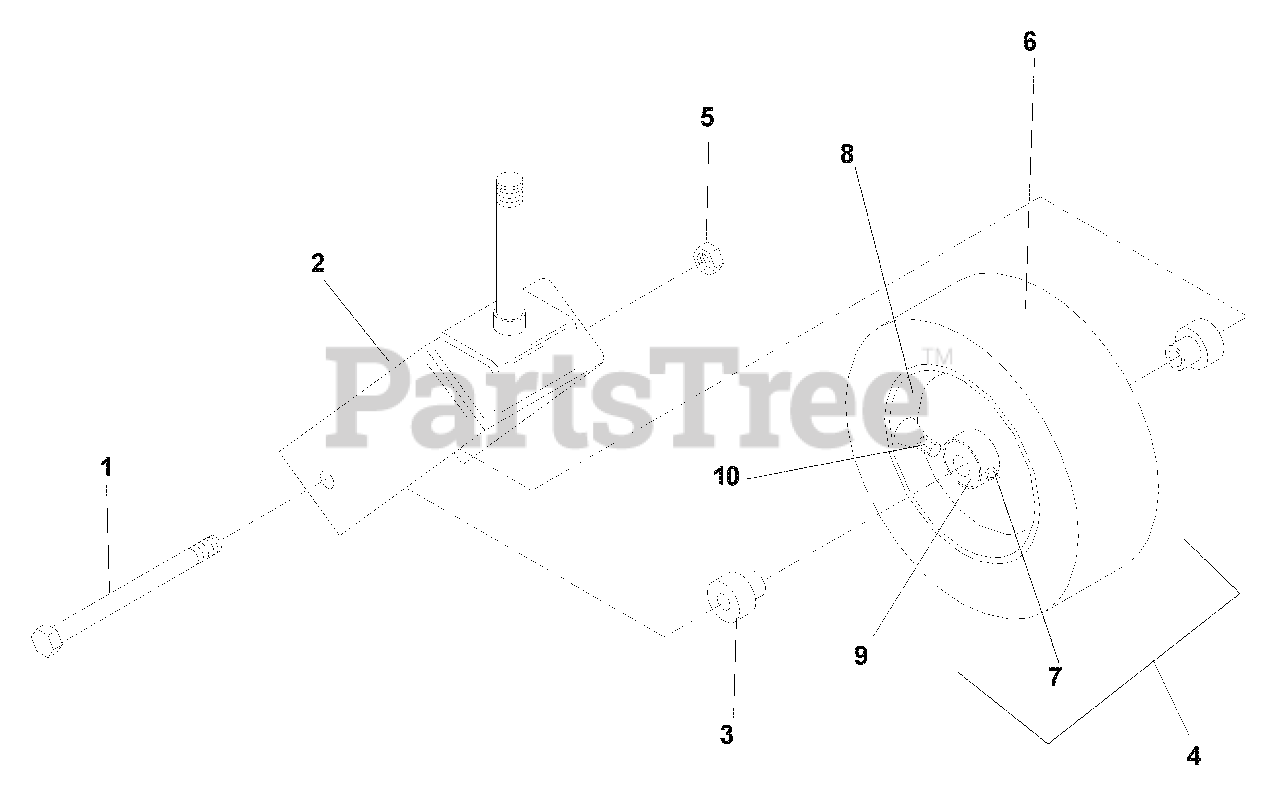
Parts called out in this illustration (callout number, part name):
1	Bolt, 1/2-13 x 9 1/2, GD. 5
2	Yoke, caster
3	Spacer, axle
4	Tire & wheel assembly
5	Nut, 1/2-13, nyloc
7	Zerk
